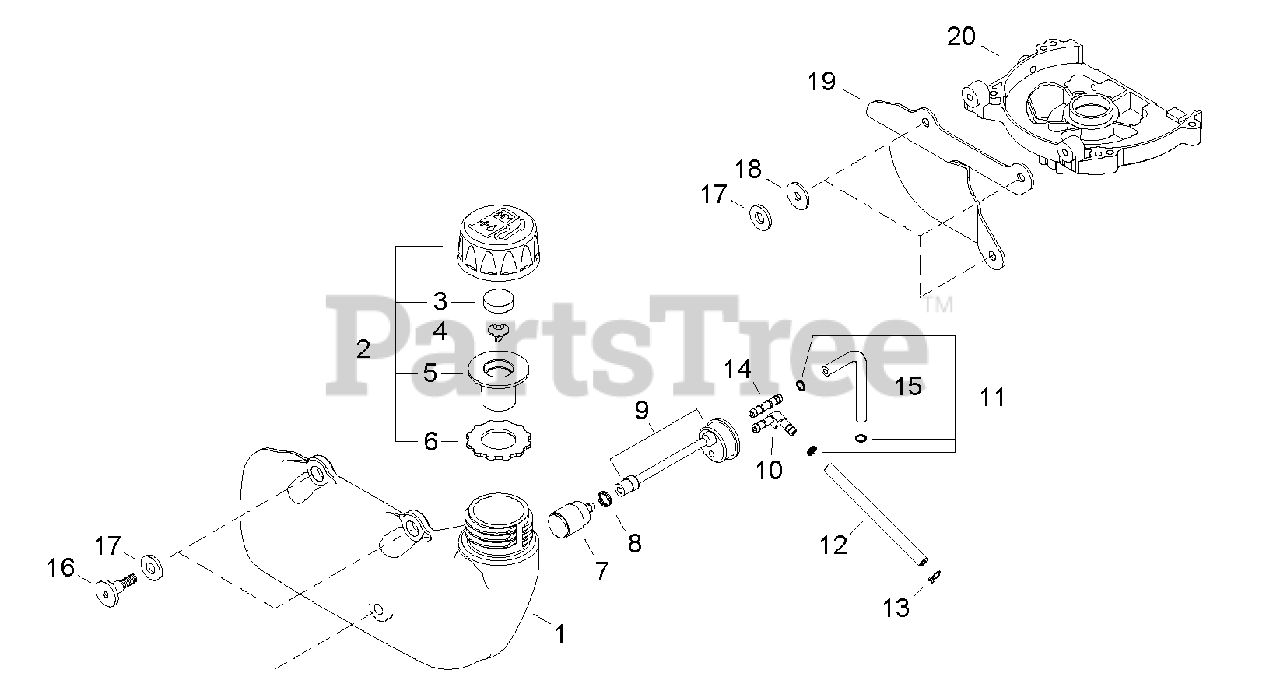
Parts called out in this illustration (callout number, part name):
1	TANK, FUEL
2	CAP ASSY
4	VENT, FUEL TANK
5	HOLDER, VENT
6	GASKET, CAP
7	FILTER, FUEL
8	CLIP - 7.8
9	FUEL PIPE ASSY
10	CONNECTOR, PIPE
11	CLIP - 6
12	PIPE - RETURN
13	CLIP - BUTTERFLY
14	CONNECTOR, PIPE
15	PIPE - FUEL
16	BOLT - 5
17	WASHER - 6
18	WASHER - 5
19	SHIELD, HEAT
20	CRANKCASE ASSY - FRONT
